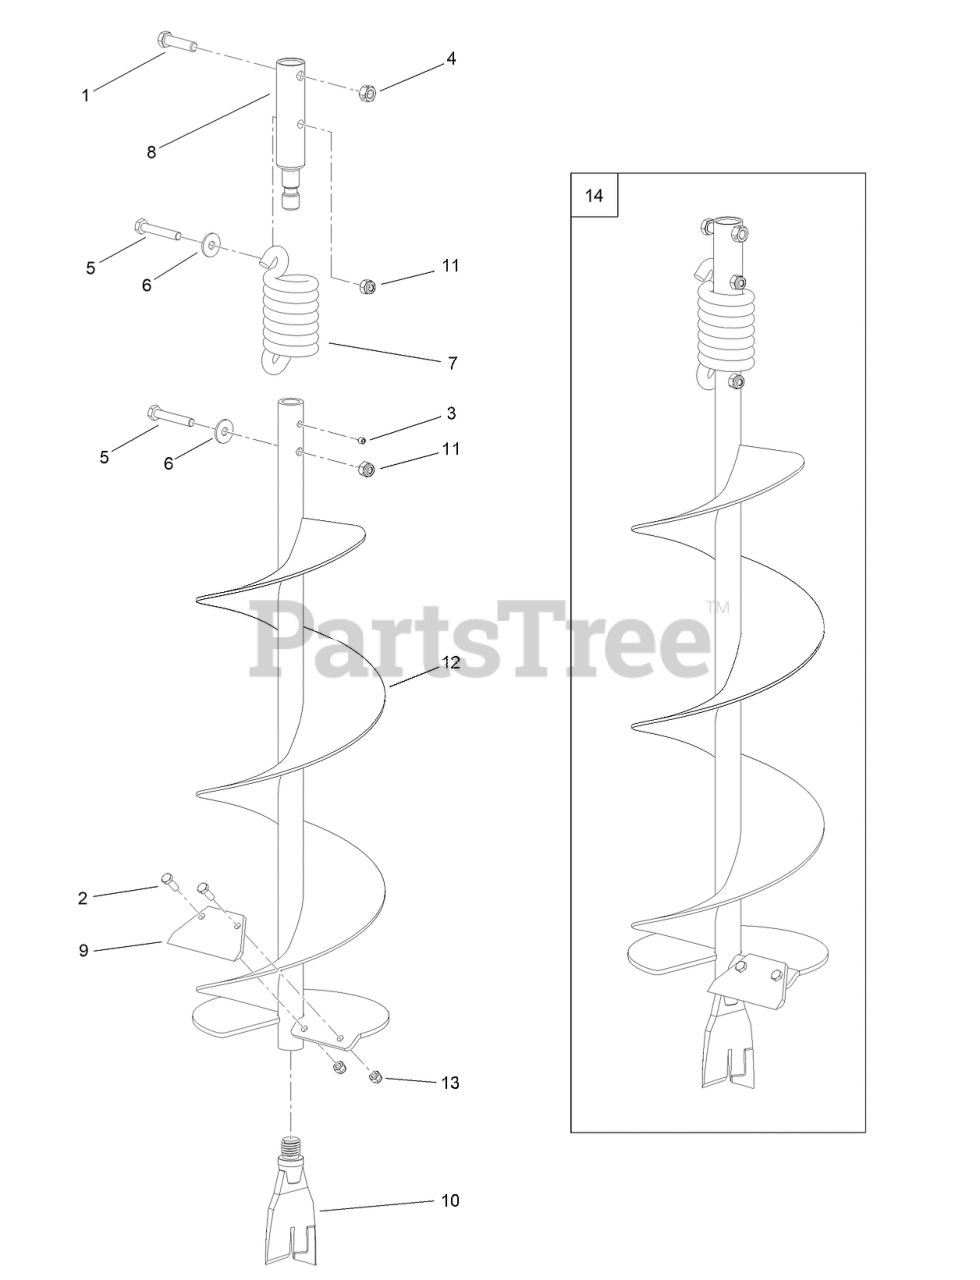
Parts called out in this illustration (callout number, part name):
1	SCREW-HHCS
2	SCREW-HHCS
3	SCREW-SCPC
4	NUT-HEX
5	SCREW-HHCS
6	WASHER-FLAT
7	SPRING-SHOCK
8	TOP-SHOCK
10	FISHTAIL POINT
11	NUT-HEX
12	AUGER-8 INCH
13	NUT-HEX
14	AUGER ASM
